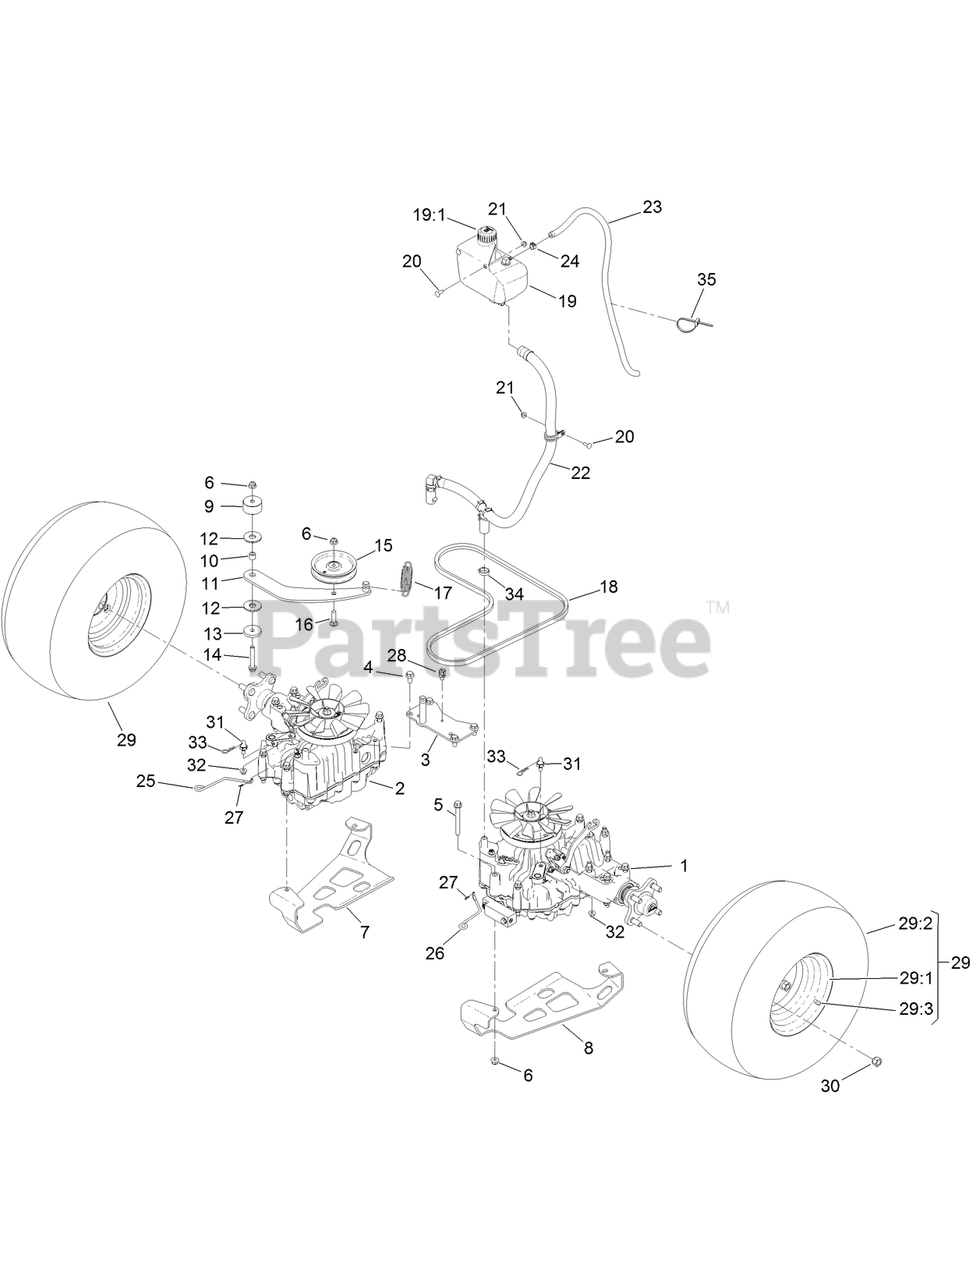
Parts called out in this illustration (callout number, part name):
1	LH TRANSMISSION ASM
2	RH TRANSMISSION ASM
3	SUPPORT-TRANSAXLE
4	SCREW-HHF
5	SCREW-HHF
6	NUT-HF, NI
7	PLATE-SKID, TRANSMISSION (RH)
8	PLATE-SKID, TRANSMISSION (LH)
9	SPACER
10	BUSHING-LEVER, LIFT
11	ARM-IDLER
12	WASHER-FRICTION, COMPOSITE
13	WASHER-PLAIN
14	SCREW-HHF
15	PULLEY-IDLER
16	SCREW-HH
17	SPRING-EXTENSION
18	BELT-V
19	TANK-HYD
19:1	CAP-VENTED
21	NUT-HF
22	HYD HOSE ASM
23	HOSE-FUEL
24	CLAMP-HOSE
25	ROD-BYPASS, RH
26	ROD-BYPASS, LH
27	PIN-HAIR
28	CLIP-TIE
29	WHEEL AND TIRE ASM
29:1	RIM-8 INCH, GRAY
30	NUT-LUG
31	SPACER-HEX
32	NUT-HF, NI
33	PIN-COTTER
34	CLAMP-DRIVE, WORM
35	TIE-CABLE
